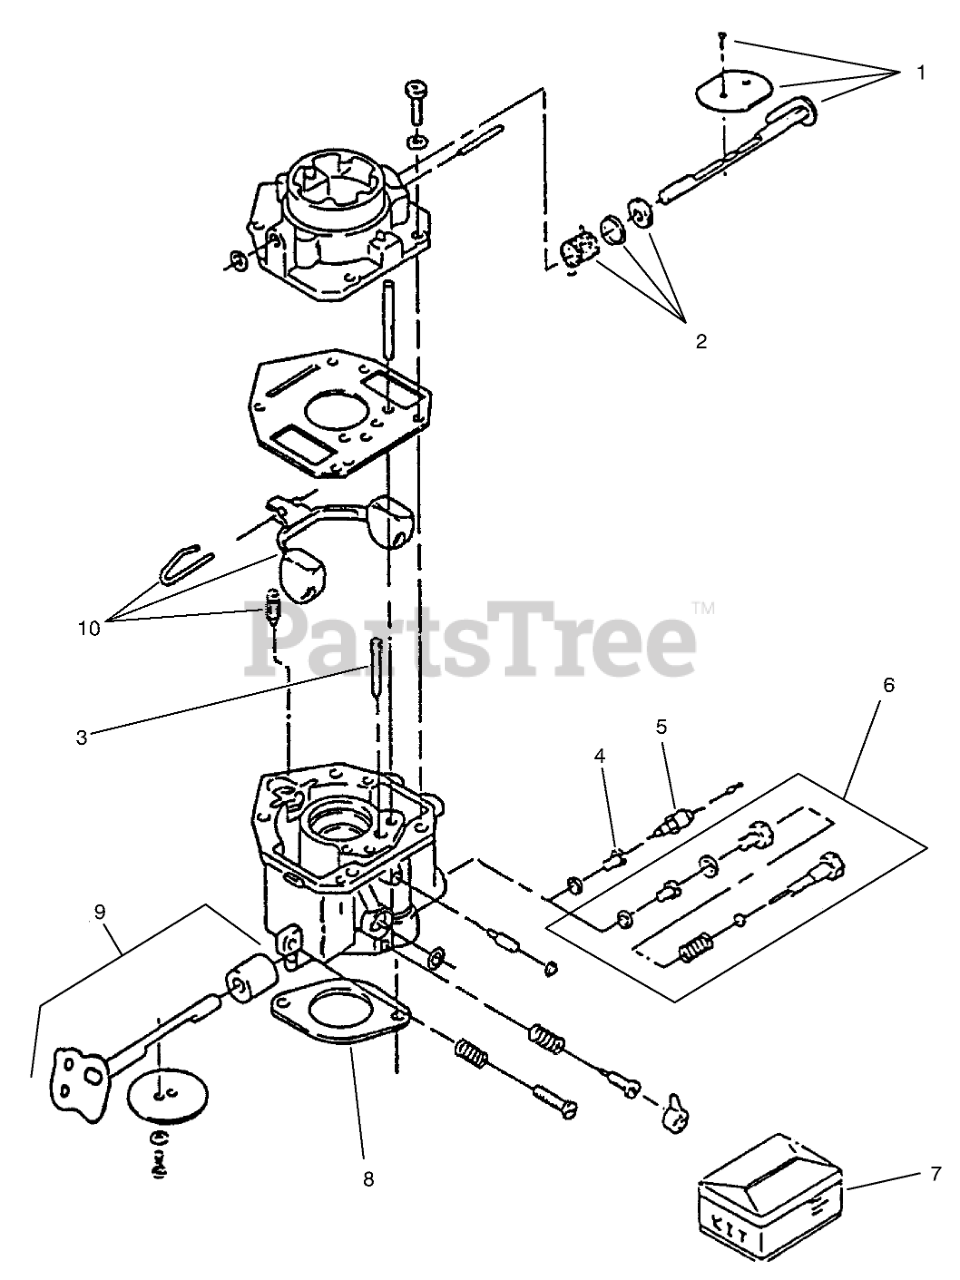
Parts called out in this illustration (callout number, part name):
1	Choke Shaft Kit
2	CHOKE-LEVER KIT
3	Idle Jet
4	POWER JET
5	Solenoid
6	FIXED-JET PKG
7	Carburetor Repair Kit
8	Gasket
9	SHAFT-THROTTLE KIT
10	Kit-Float (Includes Float Pin)
